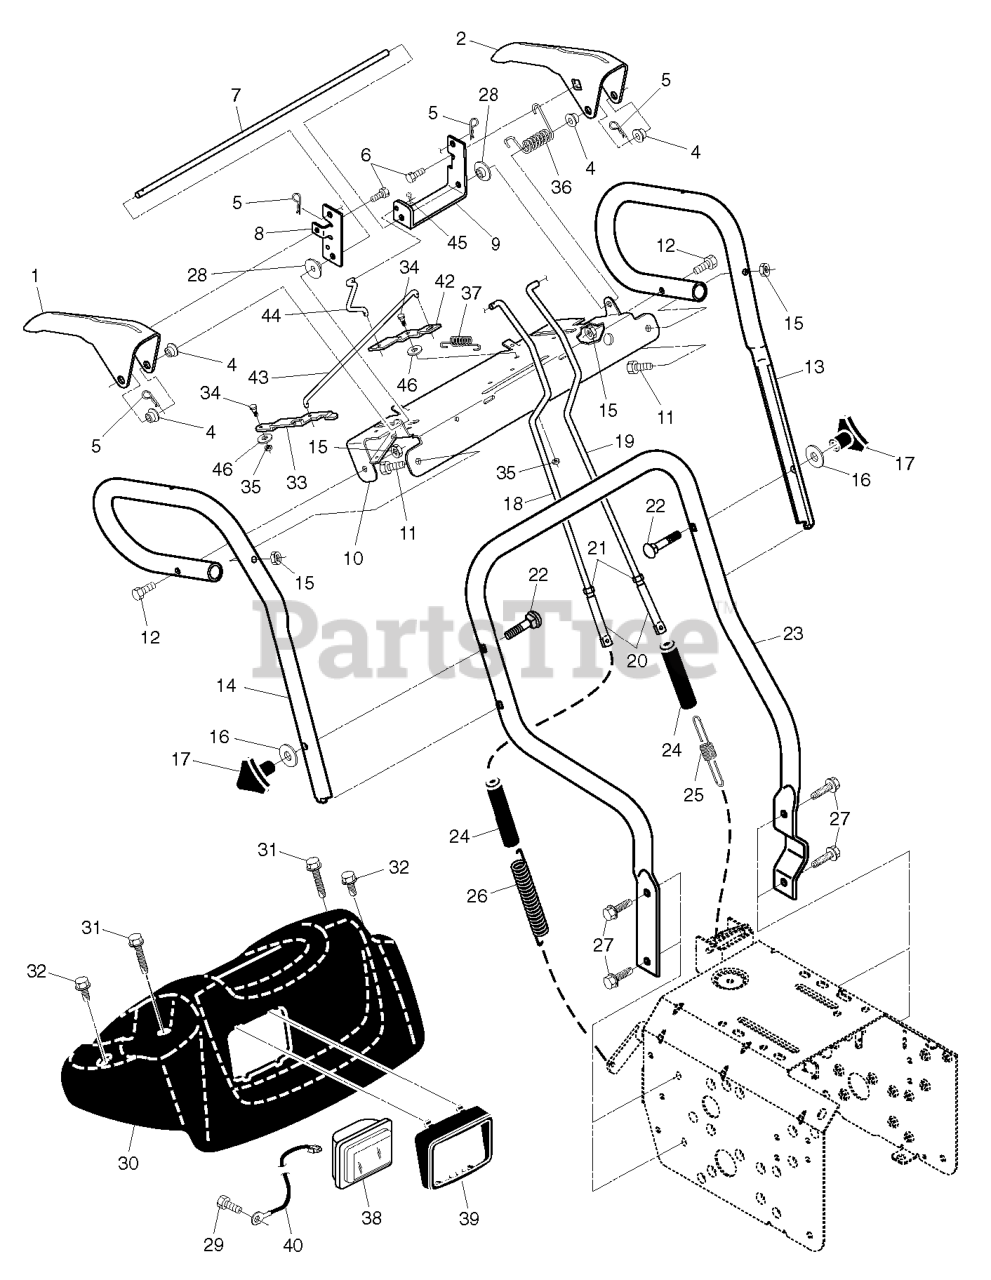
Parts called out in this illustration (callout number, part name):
1	LEVER, AUGER CONTROL, RH
2	LEVER, TRACTION DRIVE CONTROL,
4	BUSHING, FLANGE
5	SPRING RETAINER
7	ROD.INTERLOCK
8	ARM,IMPELLER ROD
9	ARM,TRACTION ROD
10	PANEL.CONTROL
11	HEX BOLT
13	HANDLE TUBE LH
14	HANDLE TUBE RH
15	NUT.LOCK.5/16-18
16	WASHER
17	KNOB.HANDLE.3/8.TRI-POINT.BLAC
18	ROD.ASM.IMPELLER
19	ROD.ASM.TRACTION.
20	ROD, END CONTROL
21	JAM NUT TI
22	BOLT 3/8-16 X 2-1/4
23	TUBE.LOWER.HANDLE.24.BLACK
24	SLEEVE, SPRING
25	SPRING, TRACTION DRIVE
26	SPRING, AUGER CONTROL
27	SCREW 3/8-16X1
28	BUSHING, IDLER PIVOT
29	SCREW.BLOWER.HOUSING.B&S
30	PANEL.CONSOLE.SNOW
31	SCREW, HEX HD TAPPING #10-24 1
32	SCREW, HEX HEAD, TAPPING
33	LATCH.INTERLOCK
34	BOLT, SHOULDER
35	NUT **
36	RP SPRING, TORSION
37	SPRING LATCH
38	HEADLIGHT.HALOGEN.SNOW
39	BEZEL.HEADLIGHT.BLACK
40	HARNESS.WIRE.HALOGEN
42	LEVER.INTERLOCK
43	ROD.LATCH.INTERLOCK
44	ROD.ASM INTERLOCK
45	RETAINER CLIP
46	WASHER, NYLON FRICTION
